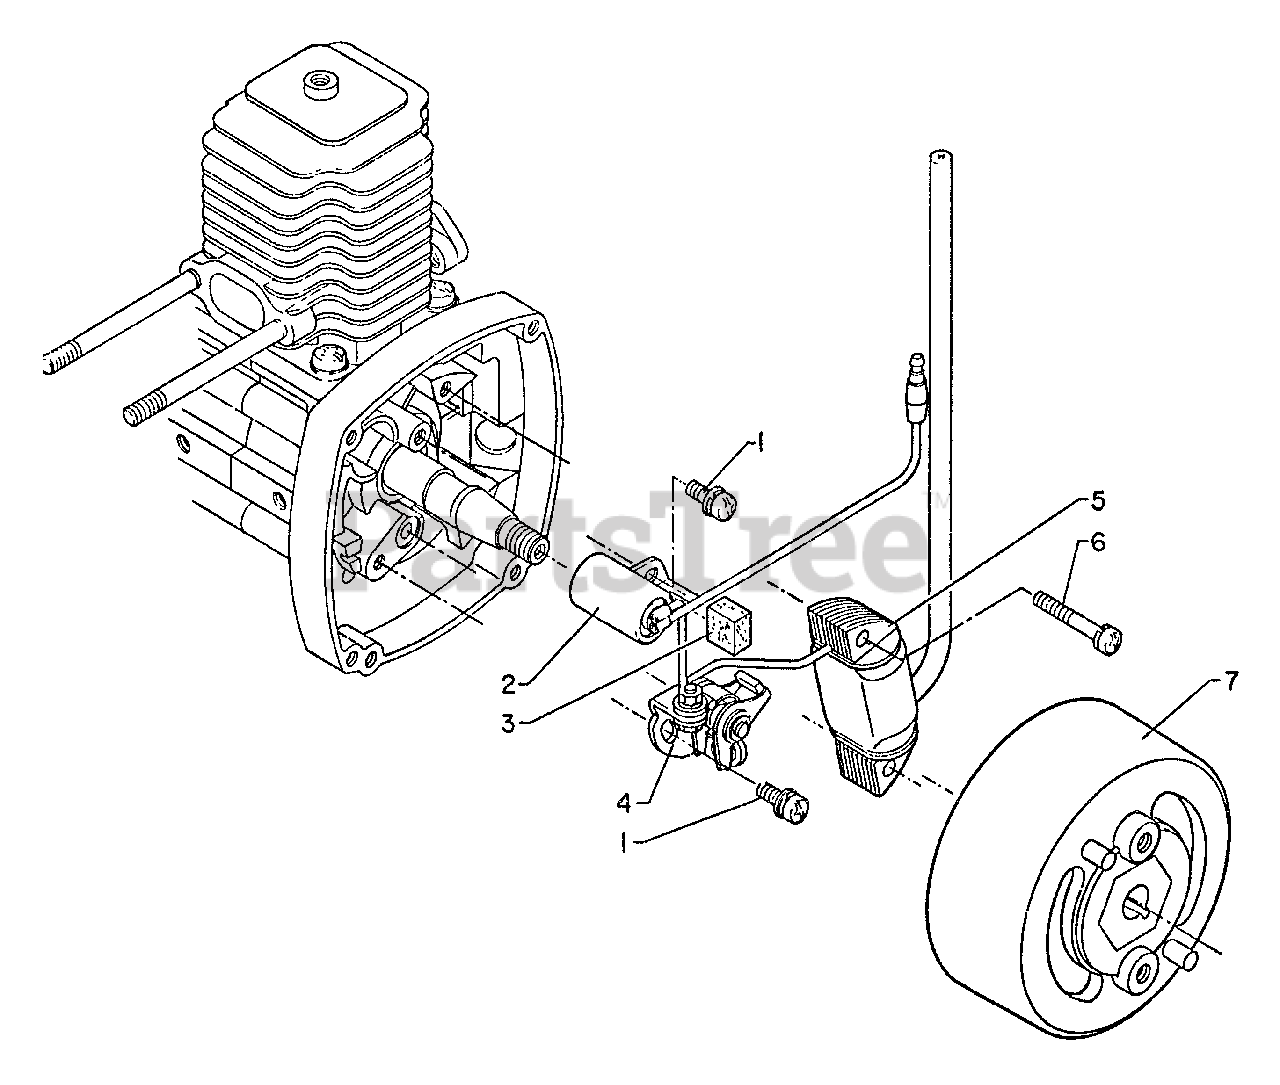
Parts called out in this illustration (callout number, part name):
1	SCREW - 4X10
2	CONDENSER
3	PAD, OIL
4	CONTACT POINT SET
5	COIL, IGNITION
6	SCREW - 4X25
7	FLYWHEEL
